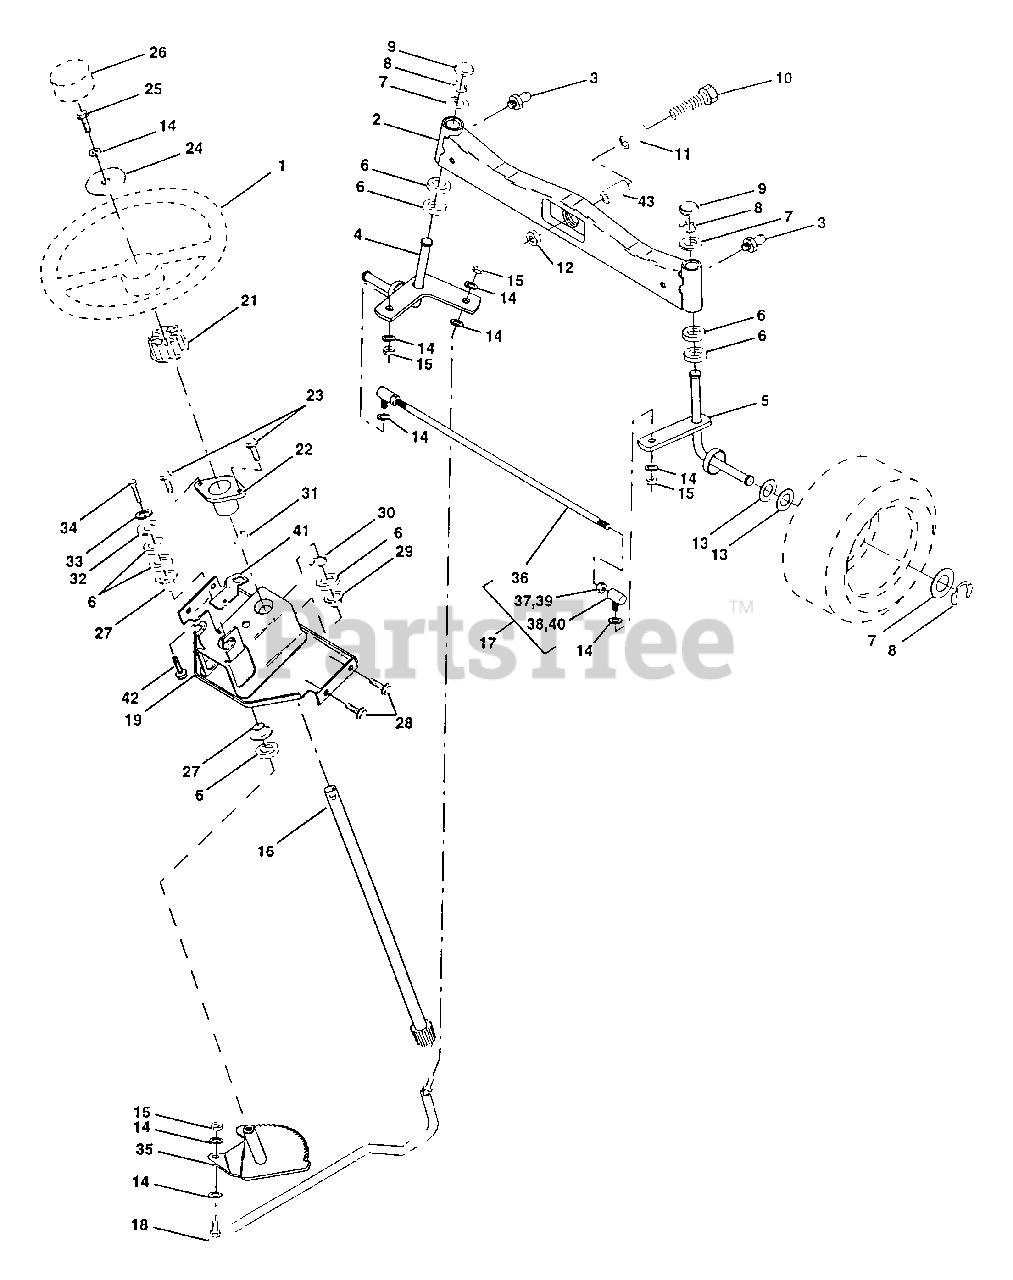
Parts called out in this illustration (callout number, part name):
1	Wheel, Steering (AYP part number)
2	Axle Asm., Front (AYP part number)
3	Fitting, Grease
4	Spindle Asm, LH (AYP part number)
5	Spindle Asm., RH (AYP part number)
6	Bearing, Race Thrust Harden
7	Washer 25/32 x 1-5/8 x 16 Ga.
8	Ring, Klip #T5304-75
9	Cap, Spindle
10	Bolt, Fin Hex 5/8-11 x 2-3/4
11	Brg. Axle
12	Nut, Lock Flange 5/8-11 Unc
13	Washer 25/32 x 1-1/4 x 16 Ga.
14	Washer, Lock Hvy Hlcl Spr 3/8
15	Nut Lock Center 3/8-24 UNF
16	Shaft Asm., Steering
17	Rod Asm., Tie Ball J Ball Vgt
18	Draglink, Ball Joint Solid Vgt (AYP part number)
19	Support Asm., Steering Vgt
21	Adapter, Wheel Steering
22	Bushing, Strg. Blk
23	Screw
24	Washer 13/32 x 2-3/8 x 8 Ga.
25	Bolt, Fin Hex 3/8-16 x 1 Gr. 5
26	Cap, Wheel Steering
27	Bearing, Col. Strg.
28	Screw Thdrol 3/8-16 x 3/4
29	Bearing, Flange
30	Ring, Klip Truarc #5304-75
31	Bushing, Nyliner Snap
32	Washer 11/32 x 1 x 10 Ga.
33	Washer, Lock Hvy Hlcl Spr 5/16
34	Bolt, Hex Hd 5/16-18 x 3/4
35	Gear, Sector Steering
36	Tie Rod (AYP part number)
37	Jam Nut RH Thread
38	Joint Asm. Ball RH Thread
39	Jam Nut LH Thread
40	Joint Asm. Ball LH Thread
41	Bracket Switch Interlock VGT97
42	Screw Thdrol 5/16-18 x 1/2 TYT
43	Spacer Axle
